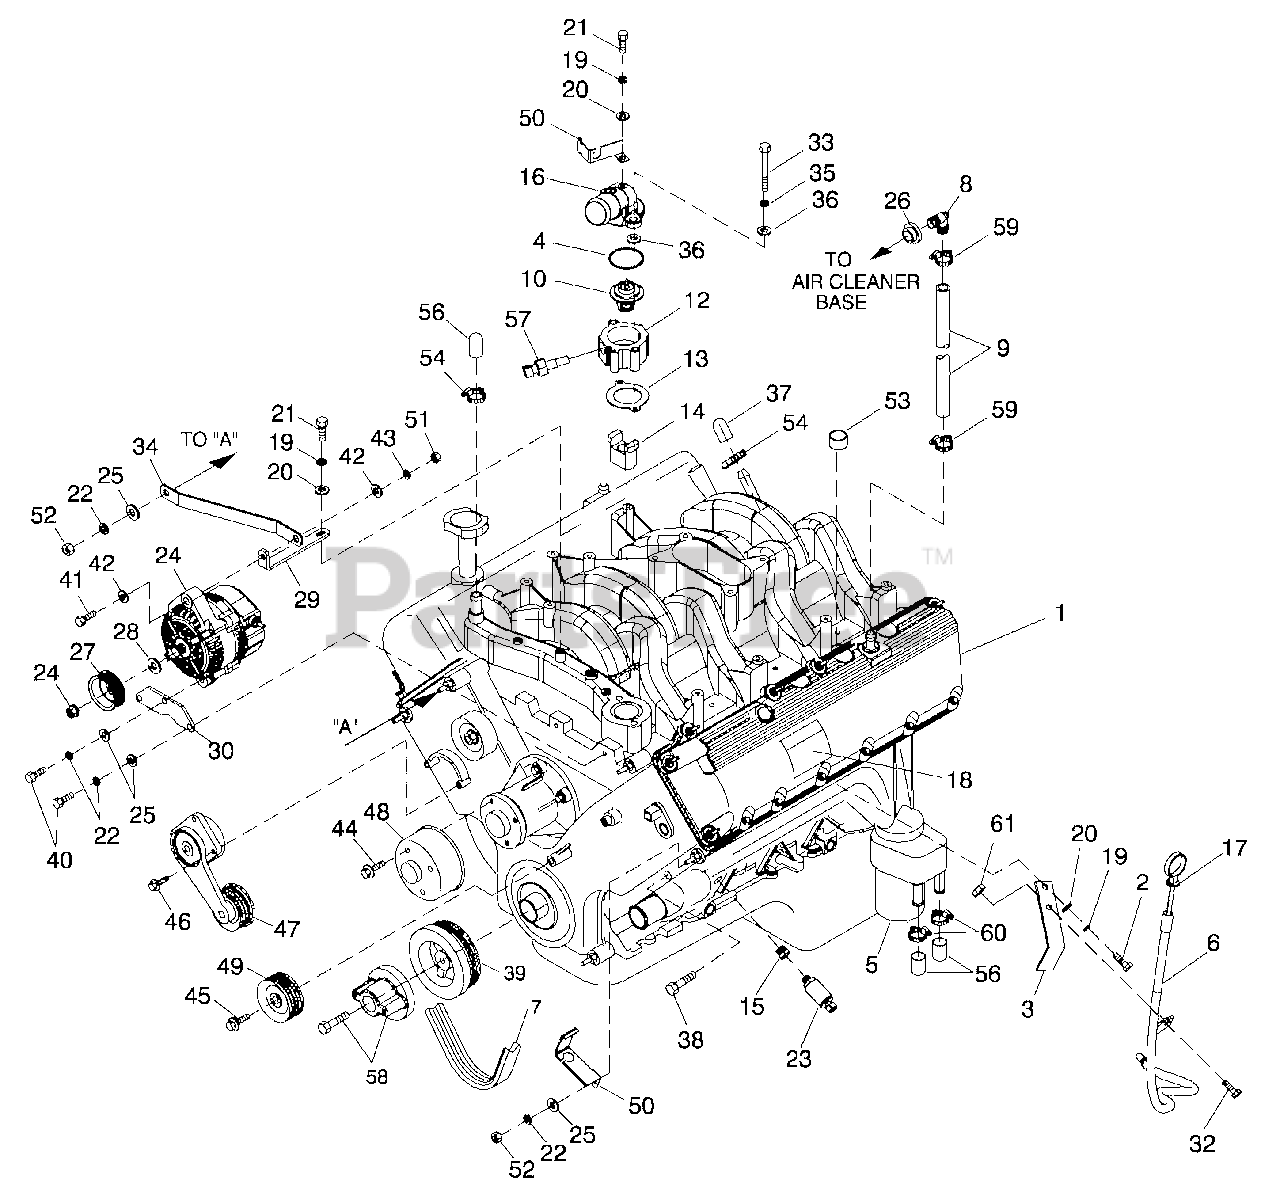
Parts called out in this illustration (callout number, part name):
1	ENGINE G5.4LG3 2009
2	SCREW HHC M6-1.0X20 C8.8
3	BRACKET DIPSTICK TUBE
4	GASKET THERMOSTAT HOUSING
5	OIL FILTER V-10 ENGINE
6	TUBE DIPSTICK
7	BELT SERPENTINE 65.0" (1800 RPM)
8	BARBE D E L 90 3/4PLASTIC
9	HOSE 3/4 I D SAE-30R2 (16.75''LG)
10	THERMOSTAT ASSY
12	A DAPTER THERMOSTAT 4.6L G3
13	GASKET THERMOSTAT 4.2L
14	SPACER COOLANT BYPASS
15	BSHG R DCR HEX 1/4 TO 1/8
16	CONNECTION WATER OUTLET
17	DIPSTICK
18	DECAL EPA STATIONARY EMERGENCY
19	WASHER LOCK M6-1/4
20	WASHER FLAT 1/4 ZINC
21	SCREW HHC M6-1.0X 20 G8.8
22	WASHER LOCK M8-5/16
23	SEN DER OIL PRESSURE 1/8&NPT
24	ALTERNATOR DC W/OUT PULLEY
25	WASHER FLAT 5/16 ZINC
26	GROMMET
27	PULLEY 80 O D DC ALTERNATOR (1800RPM)
28	SPACER DC ALTERNATOR PULLEY
29	BRKT DC ALTERNATOR UPPER
30	BRKT D C ALTERNATOR LOWER
32	SCREW HWHTF M6-1.0X16
33	SCREW HHC M8-1.25 X 140 G8.8
34	BRACKET DC ALT STABILIZER
35	WASHER LOCK M8-5/16
36	WASHER FLAT 5/16-M8 ZINC
37	CAP ANTIFREEZE 5/8"I D X 1.2"LG
38	SCREW HHCM10-1.5X60 C8.8
39	REWORK HARMONIC BALANCER 5.4L
40	SCREW HHC M8-1.25X 20 G8.8
41	SCREW HHC M10-1.5 X 45 G8.8 FT
42	WASHER FLAT 3/8-M10 ZINC
43	WASHER LOCK M10
44	SCREW WP PULLEY M8-1.25X 19
45	BOLT HEX FLH DM8-1.25X28
46	BOLT HEX FLH DM8-1.25X31
47	TENSIONER ENG. AUTOMATIC BELT
48	PULLEY WATER PUMP
49	PULLEY GROOVE D ENGINE I DLER
50	BRACKET SIGNAL CON DITIONER
51	NUT HEX M10-1.5 G8 YEL CHR
52	NUT HEX M8-1.25 G8 YEL CHR
54	CLAMP HOSE#10.56-1.06
56	CAP RUBBER
57	TEMPERATURE SEN DER, DELPHI
59	CLAMP HOSE#10.56-1.06
60	CLAMP HOSE#12.50-1.25
61	NUT HEX M8-1.25 G8 CLEAR ZIN
